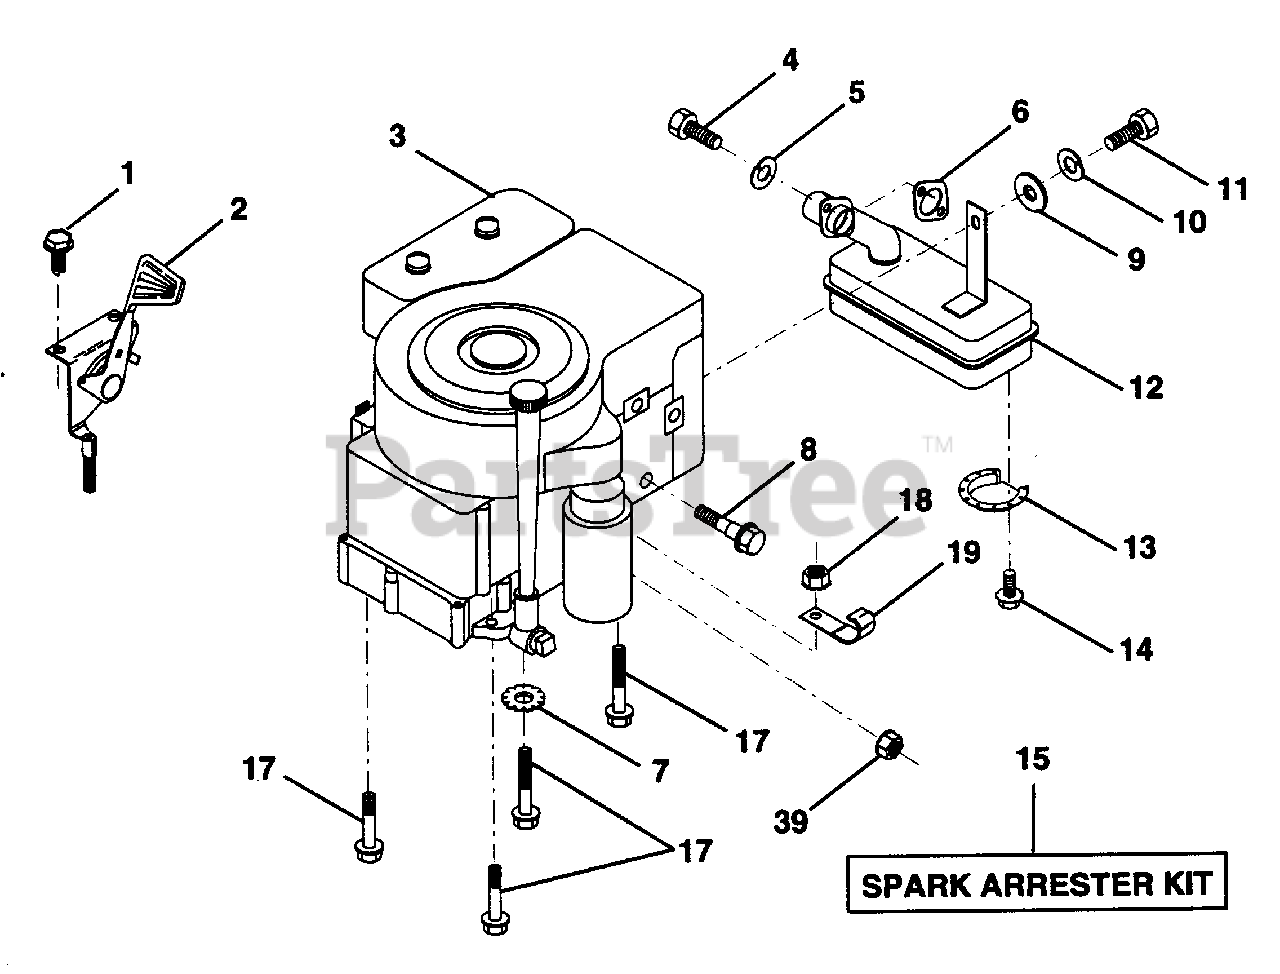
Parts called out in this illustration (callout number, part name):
1	Screw, Hex Thd. Cut 1/4-20 x 1/2 (AYP part number)
2	Control, Throttle (AYP part number)
4	Screw, Hex, Cap 5/16-18 x 3/4 (AYP part number)
5	Washer, Lock Heavy Helical Spring 5/16 (AYP part number)
6	Gasket, Exhaust (AYP part number)
7	Washer, Lock Ext. Tooth 3/8 (AYP part number)
8	Bolt, Shoulder 5/16 (AYP part number)
9	Washer 5/16 x 3/4 x 16 (AYP part number)
10	Washer, Lock Hvy Hlcl Spring 1/4 (AYP part number)
12	Muffler (AYP part number)
13	Deflector, Muffler (AYP part number)
14	Screw, Spiderloc Hex Hd #8 x 1/2 (AYP part number)
15	Arrester, Spark (Optional equipment) (AYP part number)
17	Screw, Hex Washer Head, Thdrol. 3/8-16 x 1-1/2 (AYP part number)
18	Nut, Hex Keps 3/8 (AYP part number)
19	Clip, Fuel Line (AYP part number)
39	Nut, Keps Hex 1/4-20 (AYP part number)
